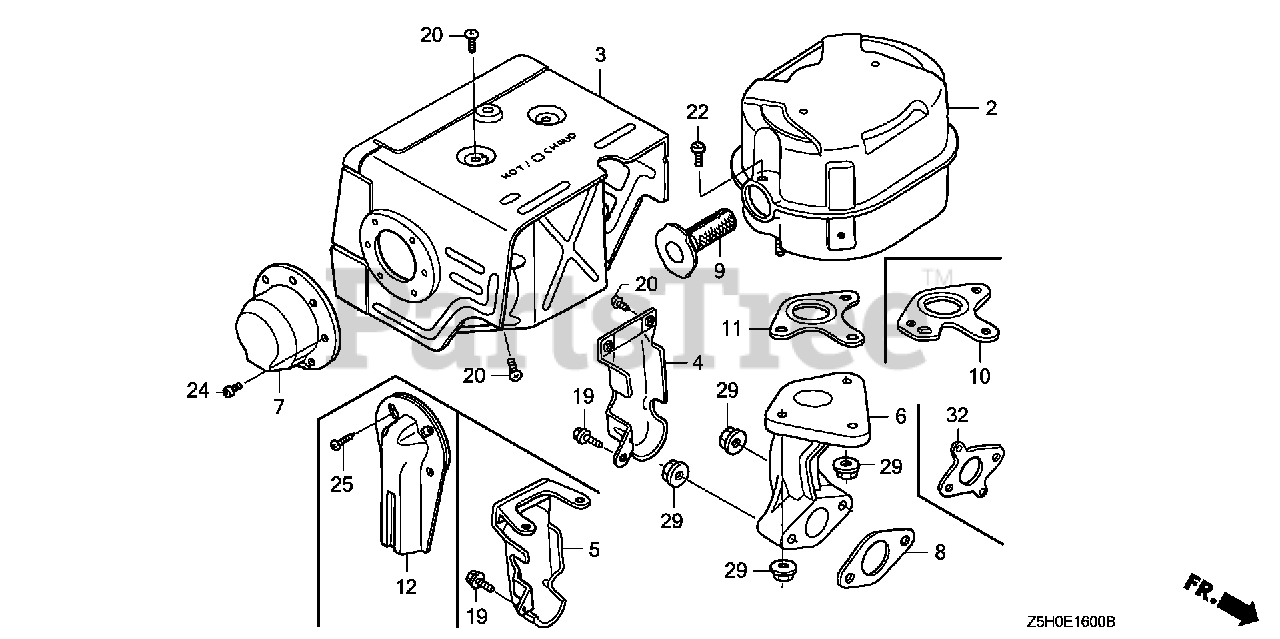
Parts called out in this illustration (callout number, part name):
2	MUFFLER
3	PROTECTOR, MUFFLER (STD)
4	PROTECTOR, EX. PIPE
7	CAP, MUFFLER
8	GASKET, EX. PIPE Use up to Engine SN 2949254.
8	GASKET, EX. PIPE (WACKER)
9	ARRESTER, SPARK
10	GASKET, MUFFLER (ARRESTER)
10	GASKET, MUFFLER (ARRESTER)(THAI LEAKLESS)
19	BOLT, FLANGE (6X12) (CT200)
20	SCREW, TAPPING (5X8)
22	SCREW, TAPPING (4X6) (TO INSTALL OPTIONAL SPARK ARRESTER)
24	SCREW, TAPPING (4X6) (TO INSTALL OPTIONAL SPARK ARRESTER)
29	NUT, FLANGE (8MM)
